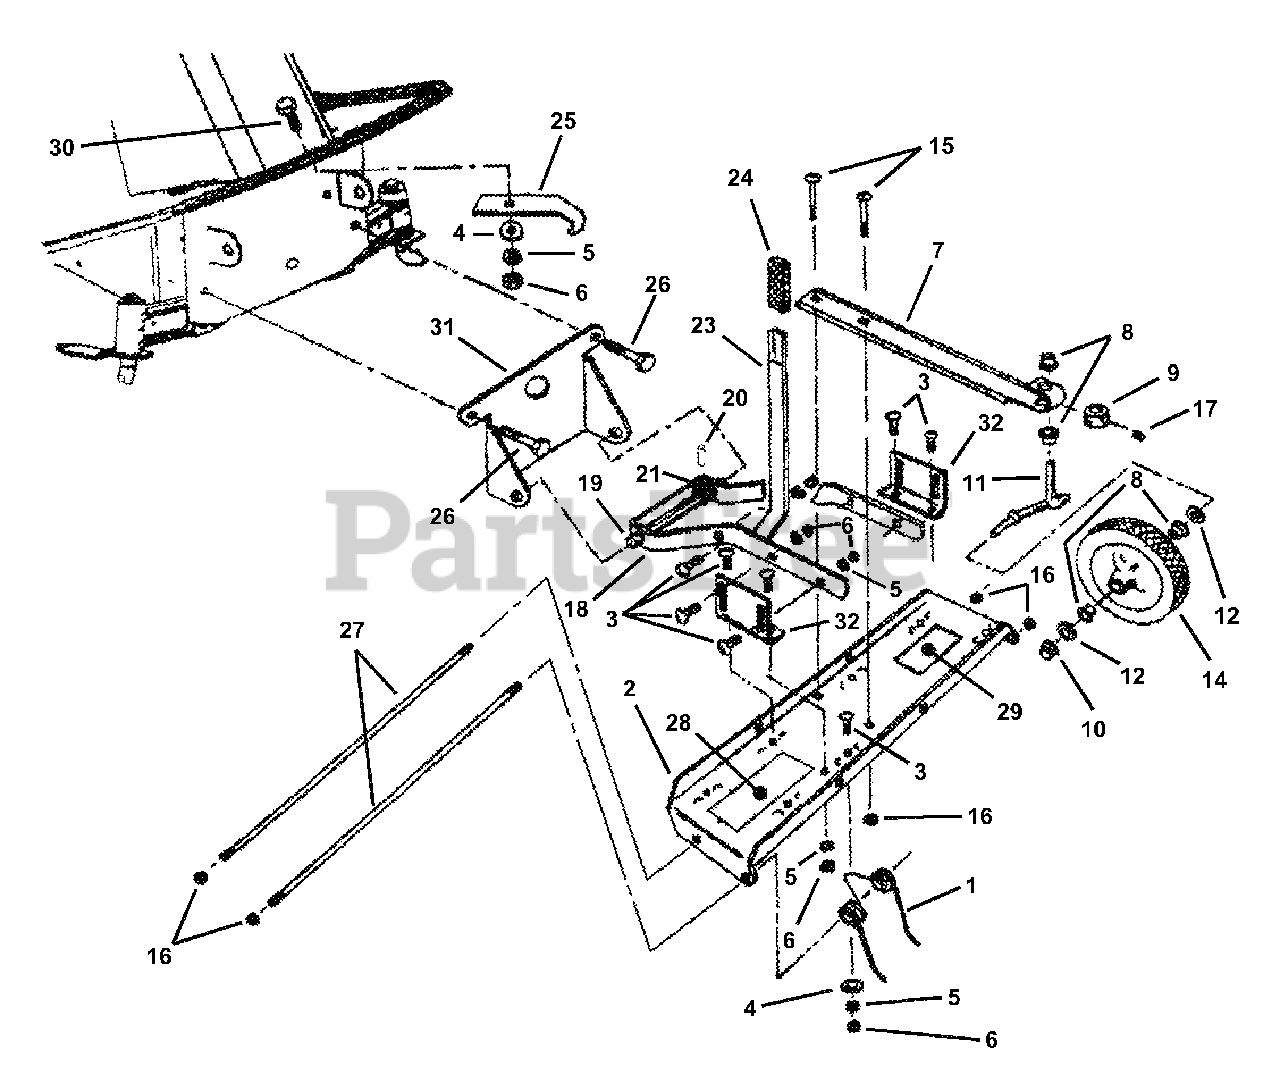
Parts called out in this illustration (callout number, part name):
1	TINE
2	TRAY, Tine (30.5")
3	BOLT, 5/16-18 x 1" Short Neck Carriage
4	WASHER, 5/16" I.D. Flat
5	WASHER, 5/16" Split Lock
6	NUT, 5/16-18 Hex
7	SUPPORT, Wheel
8	BEARING, Nylon
9	LOCKING COLLAR
10	PUSH NUT, 1/2"
11	AXLE
12	WASHER, 1/2" Flat
14	GAUGE WHEEL
15	BOLT, 1/4-20 x 1-3/4" Square Neck Carriage
16	NUT, 1/4-20 Hex Top Lock
17	SCREW, 5/16-18 x 1/4" Set
18	FRAME, Main
19	ROD, Mounting
20	PIN, 1/4 x 1-3/4" Roll
21	SPRING
23	HANDLE, Lift
24	GRIP, Vinyl
25	BRACKET, Transport Lock
26	BOLT, 3/8-16 x 3" Hex
27	ROD, Safety
28	DECAL, Thatcherizer
29	DECAL, Instructions
30	BOLT, 5/16-18 x 3/4" Hex Flange Lock
31	BRACKET, Attaching
32	BRACKET, Tray
